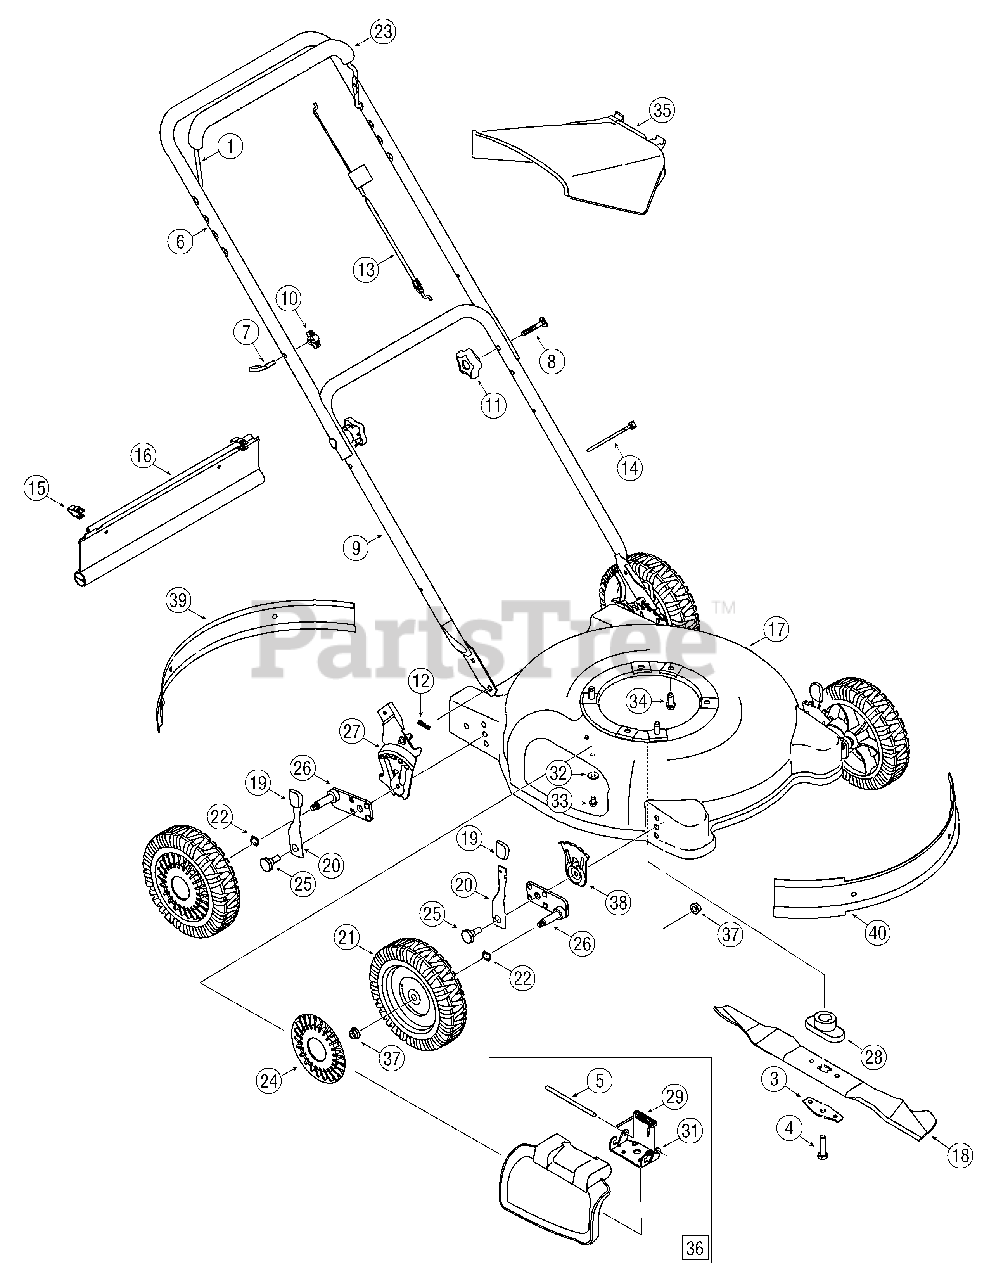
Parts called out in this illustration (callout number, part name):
2	Saddle Washer
3	Blade Bell Support
5	Hinge Pin
7	Rope Guide
8	Carriage Bolt
11	Star Knob
12	Hairpin Clip
13	Control Cable 37.25"
14	Cable Tie
15	Hinge Clip
16	Trail Shield
19	Height Adjustment Knob
20	Spring Lever
21	Wheel Assembly 8 x 2.125
22	Wave Washer
23	Deluxe Bail Cover
24	Hubcap: Radial Spoke Gray
25	Shoulder Bolt
26	Pivot Arm Assembly - RH
26	Pivot Arm Assembly - LH
27	Handle Bracket Assembly RH
27	Handle Bracket Assembly LH
28	Blade Adapter
28	Blade Adapter Kit includes 748-0376C adapter
29	Torsion Spring
30	Height Adjust. Assembly LH
30	Height Adjust. Assembly RH
32	Bell Washer
33	Hex Washer Hd. TT Screw
34	TT Sems Screw
35	Chute Deflector
36	Mulching Plug Assembly
37	Hex Lock Nut
38	Height Adjustment Plate
